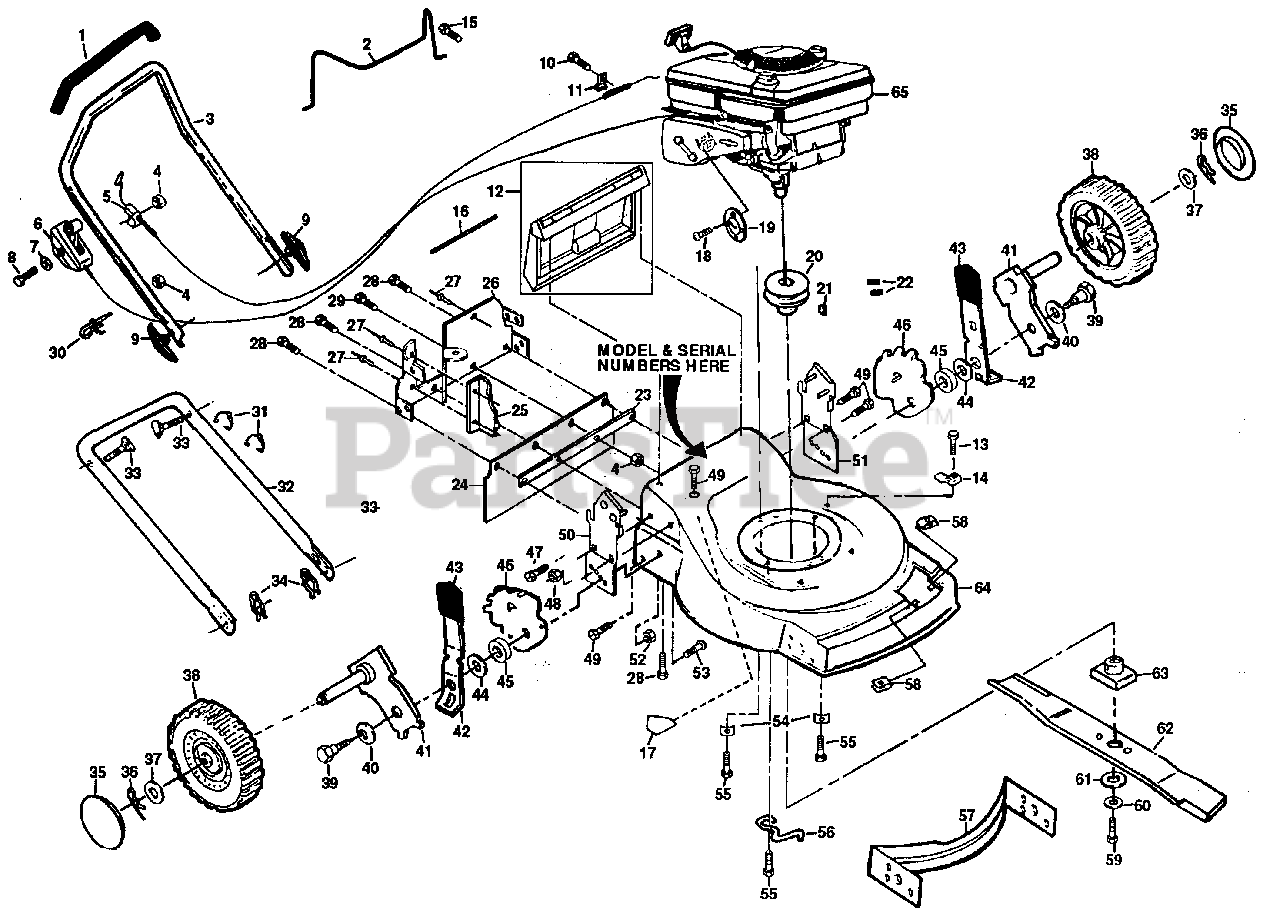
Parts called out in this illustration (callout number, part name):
1	Handle Grip (AYP part number)
2	Control Bar (AYP part number)
3	Upper Handle (AYP part number)
4	Locknut (AYP part number)
5	Engine Zone Control Cable (AYP part number)
6	Throttle Control
7	Washer (AYP part number)
8	Machine Screw 1/4-20 x 2-1/8 (AYP part number)
9	Handle Knob (AYP part number)
10	Screw #10 x 5/8 (AYP part number)
11	Cable Clamp (Engine) (AYP part number)
12	Rear Door Kit (AYP part number)
13	Hex Washer Head Screw #10-24 x 1/2 (AYP part number)
14	Housing Cable Guide (AYP part number)
15	Self-tapping Screw #10-24 x 5/8 (AYP part number)
16	Hinge Rod (AYP part number)
17	Danger Decal (AYP part number)
18	Screw #8-32 x 3/8 (AYP part number)
19	Muffler Deflector
20	Engine Pulley (AYP part number)
21	Hi Pro Key #50 (AYP part number)
22	Set Screw 1/4-20 x 5/1 (AYP part number)
23	Backing Strip (AYP part number)
24	Rear Skirt (AYP part number)
25	Side Baffle (AYP part number)
26	Back Plate (AYP part number)
27	Pop Rivet (AYP part number)
28	Hex Head Tapping Screw 1/4-20 x 1/2 (AYP part number)
29	Hex Head Machine Screw 1/4-20 (AYP part number)
30	Rope Guide (AYP part number)
31	Cable Clip (AYP part number)
32	Lower Handle (AYP part number)
33	Handle Bolt
34	Hairpin Cotter (AYP part number)
35	Hubcap (AYP part number)
36	Retainer Clip (AYP part number)
37	Washer (AYP part number)
38	Wheel & Tire Assembly 9.00 x 2.00 (AYP part number)
39	Shoulder Bolt (AYP part number)
40	Belleville Washer (AYP part number)
41	Axle Arm (AYP part number)
42	Selector Spring (AYP part number)
43	Selector Knob (AYP part number)
44	Washer (AYP part number)
45	Spacer (AYP part number)
46	Wheel Adjusting Bracket (AYP part number)
47	Self-tapping Screw 5/16-18 x 3/4 (AYP part number)
48	Locknut 5/16-18 (AYP part number)
49	Hex Tapping Screw 1/4-20 x 1/2 (AYP part number)
50	Handle Bracket (Right) (AYP part number)
51	Handle Bracket (Left) (AYP part number)
52	Locknut 3/8-16 (AYP part number)
53	Carriage Bolt 5/16-18 x 5/8 (AYP part number)
54	Engine Washer (AYP part number)
55	Hex Head Thread Rolling Screw 3/8-16 x 1 (AYP part number)
56	Belt Snubber (AYP part number)
57	Front Baffle (AYP part number)
58	Speed Nut (U Type) (AYP part number)
59	Hex Head Machine Screw 3/8-24 x 1-3/8 Gr. 8
60	Helical Lock Washer (AYP part number)
61	Hardened Washer (AYP part number)
62	Blade 22"
63	Blade Adapter
64	Lawn Mower Housing Kit (Inc.17) (AYP part number)
